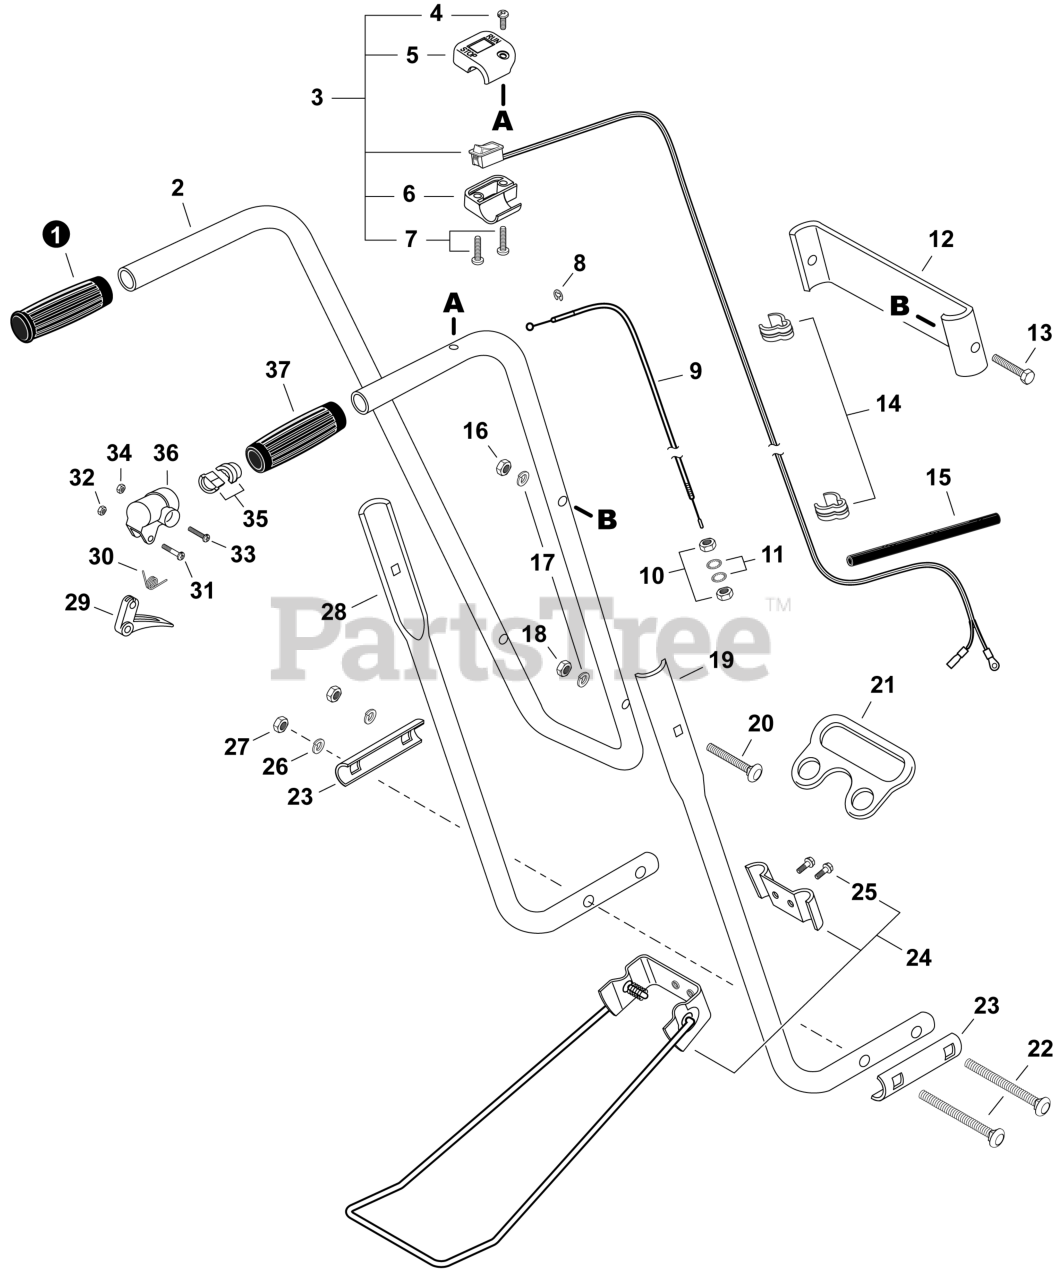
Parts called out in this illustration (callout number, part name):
1	GRIP, HANDLE
2	HANDLE, UPPER
3	SWITCH KIT, ON-OFF
4	SCREW 5x10
5	COVER, SWITCH
6	CASE, SWITCH
9	CABLE, THROTTLE
11	WASHER, LOCK 6 MM
12	SUPPORT, HANDLE
13	BOLT 1/4"x1-1/4"
16	NUT, LOCK 1/4
17	WASHER, SPRING
19	HANDLE, LOWER - RIGHT
21	HANDLE, FRONT
22	BOLT 1/4"-20x3-1/4"
23	PLATE, EYE
24	KICK STAND KIT
25	BOLT 6x12
26	WASHER, SPRING
27	NUT, LOCK 1/4
28	HANDLE, LOWER - LEFT
29	TRIGGER, THROTTLE
33	SCREW 5x25
34	NUT, LOCK M5
35	HOLDER, CABLE
36	BRACKET, TRIGGER
37	GRIP, HANDLE
